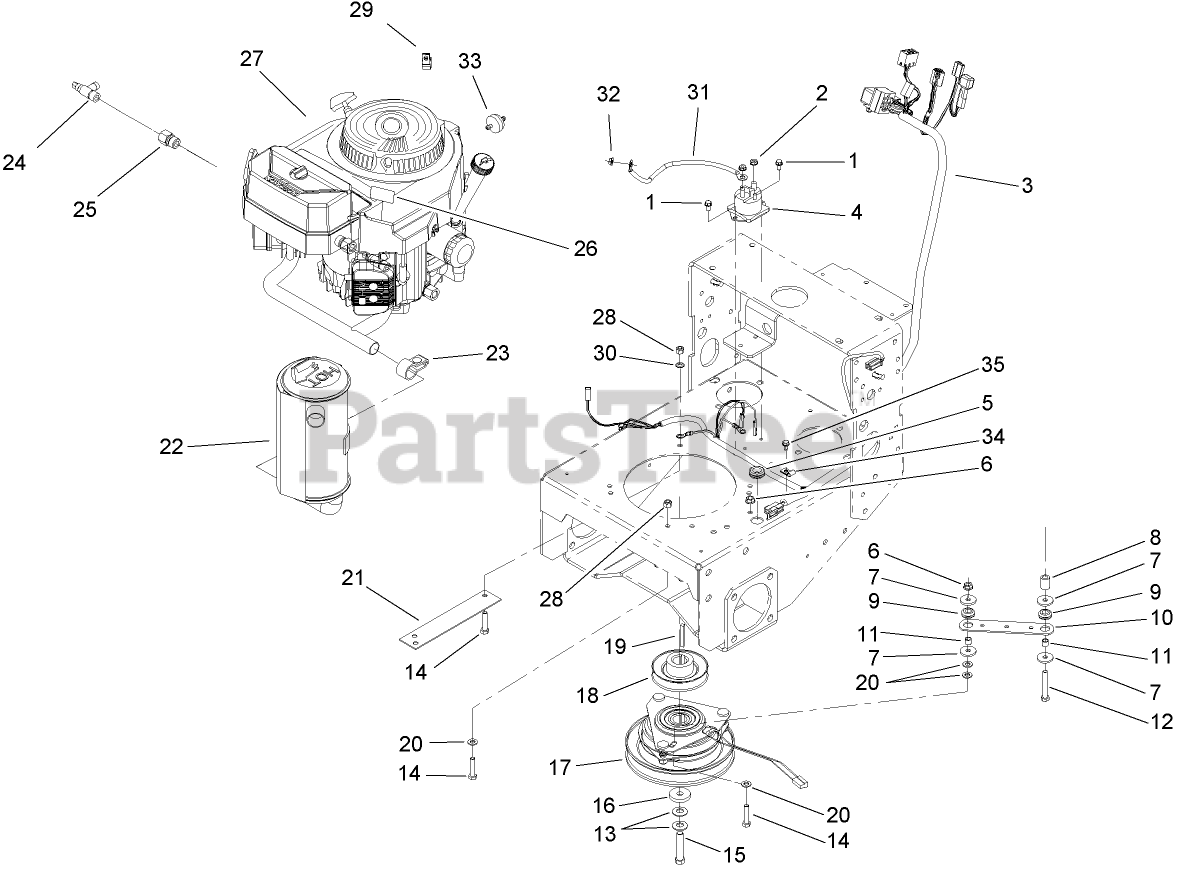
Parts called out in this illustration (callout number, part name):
1	SCREW-HWH
2	NUT-KEPS
3	HARNESS-WIRE
4	SOLENOID
5	GROMMET
6	NUT-HF
7	WASHER
8	TUBE-RETAINER
9	GROMMET
10	STRAP-CLUTCH, BRAKE
11	SPACER
12	SCREW-HH
13	WASHER-SPRING
14	SCREW-HH
15	SCREW-HH
16	WASHER
17	CLUTCH / BRAKE ASM
18	Pulley
19	KEY-SQUARE
20	WASHER-PLAIN
21	COVER-PULLEY
22	MUFFLER
23	CLAMP-MUFFLER
24	Valve-Drain, Oil
25	Adapter
26	DECAL-WARNING
28	NUT-LOCK, NI
29	CLAMP-CABLE
30	WASHER-LOCK
31	CABLE-BATTERY
32	NUT-KEPS
33	FILTER-FUEL
34	CLIP-CLOSED, INSULATED
35	SCREW
